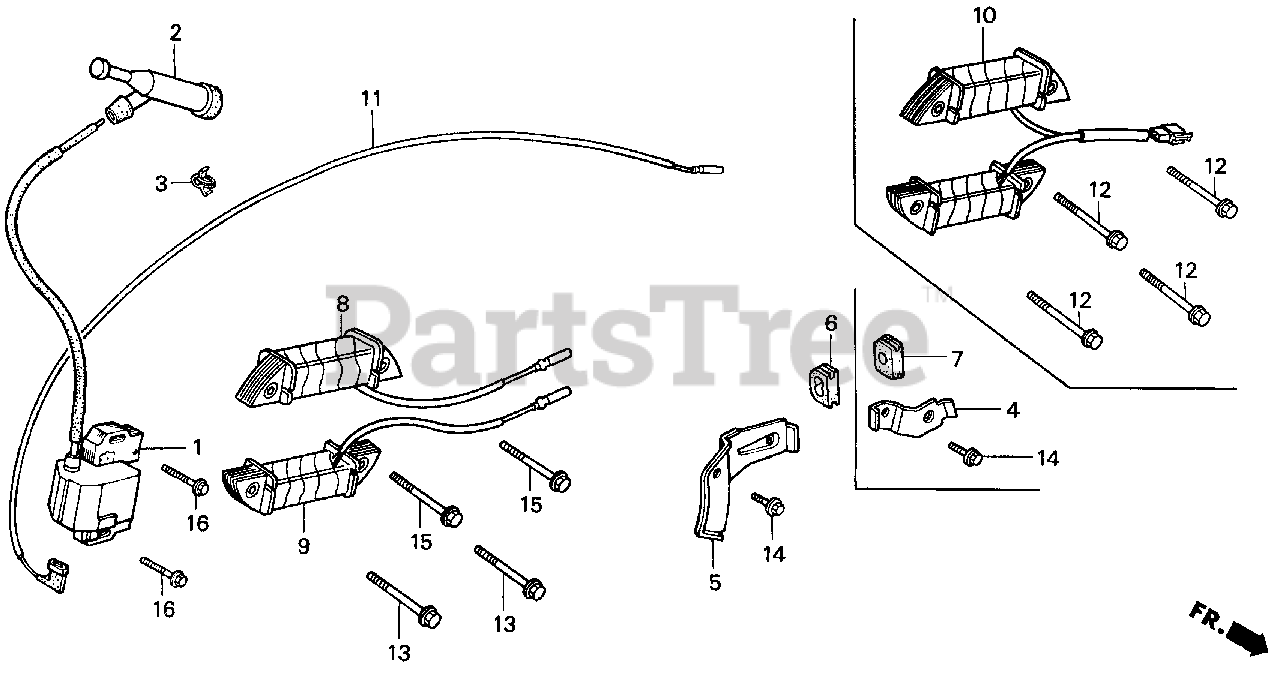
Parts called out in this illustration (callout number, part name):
1	COIL ASSY., IGNITION
2	CAP ASSY., NOISE SUPPRESSOR
6	GROMMET, WIRE
11	WIRE, STOP SWITCH (430MM)
16	BOLT, FLANGE (6X28)
